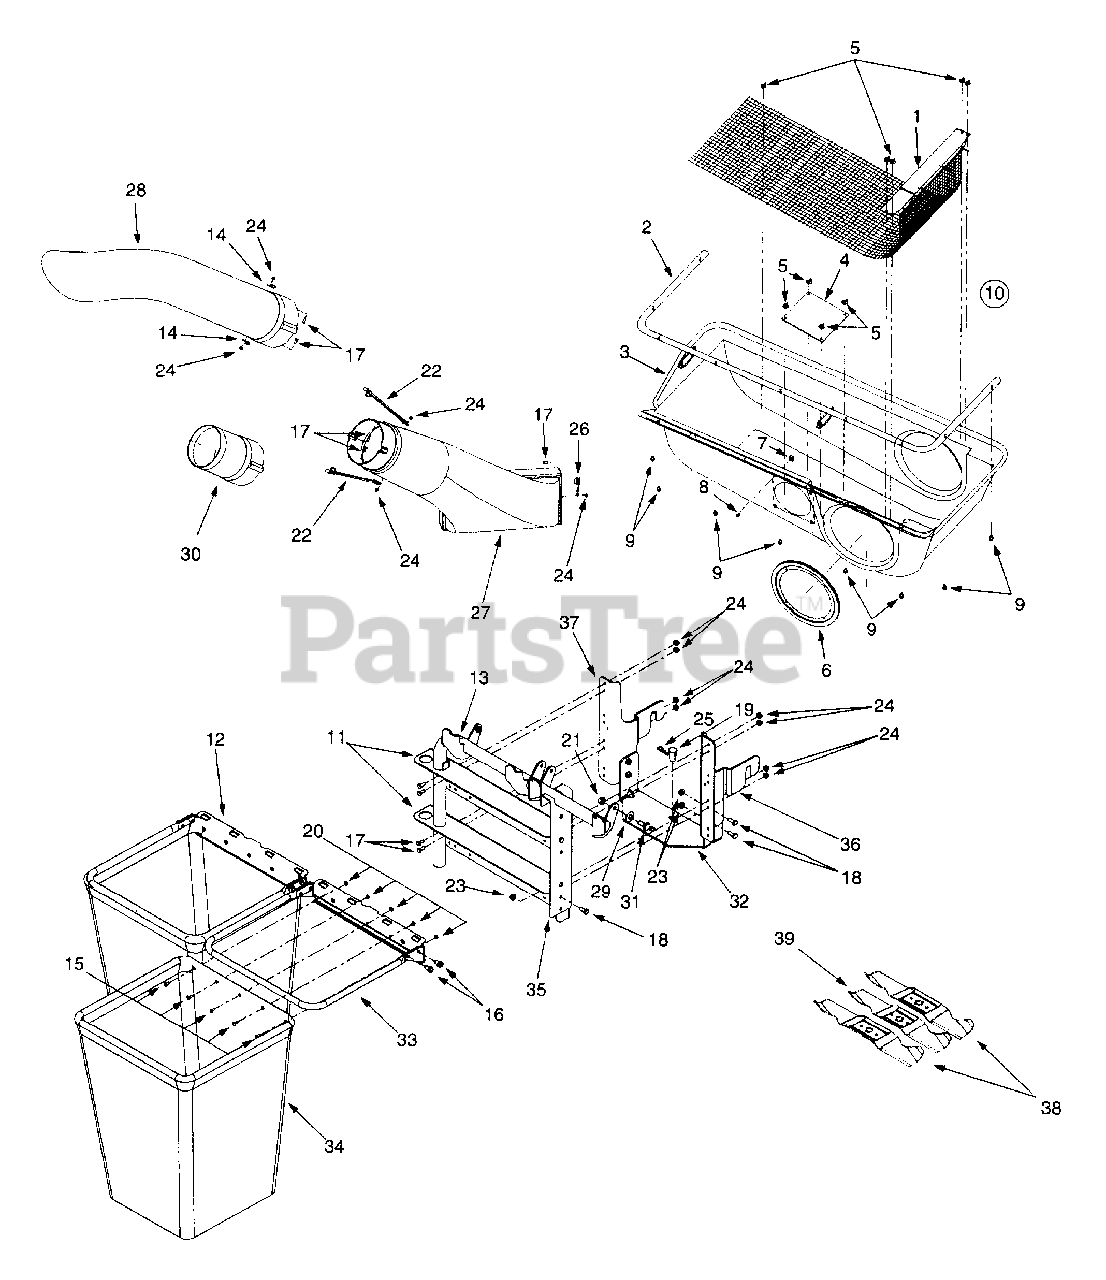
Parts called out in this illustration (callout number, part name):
3	Grass Catcher Cover (Model 601)
4	Plastic Plate, 1/8 x 5.6 sq.
5	Zip Twist Fastener
6	Tube Seal (Model 601)
7	U-Type Speed Nut, #10-24
8	Screw, #10-16 x .5 (Model 601)
9	Hex Screw, 1/4-20 x.5 (Model 601)
10	Cover Assembly (Model 601)
14	Retainer Hook Bracket
15	Screw, #10-24 x .5
16	Self Tapping Screw, 5/16-18 x .625
17	Hex Cap Screw, 1/4-20 x .62
18	Hex Cap Screw, 5/16-18 x .75
19	Clevis Pin
20	Hex Sems Nut, 10-24
21	Hex Flange Lock Nut, 3/8-16
22	Retainer Strap Assembly
23	Hex Flange Lock Nut, 5/16-18
24	Hex Flange Lock Nut, 1/4-20
25	Internal Cotter Pin, .148 x 3
26	Retainer Strap Assembly
27	Discharge Chute (Model 601)
28	Chute Tube (Model 601)
29	Bell Washer (Model 601)
30	Extension Tube (Model 601)
31	Shoulder Screw, .50 x .27, 3/8-16
34	Bag
38	Star Center Blade, 16.28 (Model 602)
39	Star Center Blade, 14.88 (Model 602)
